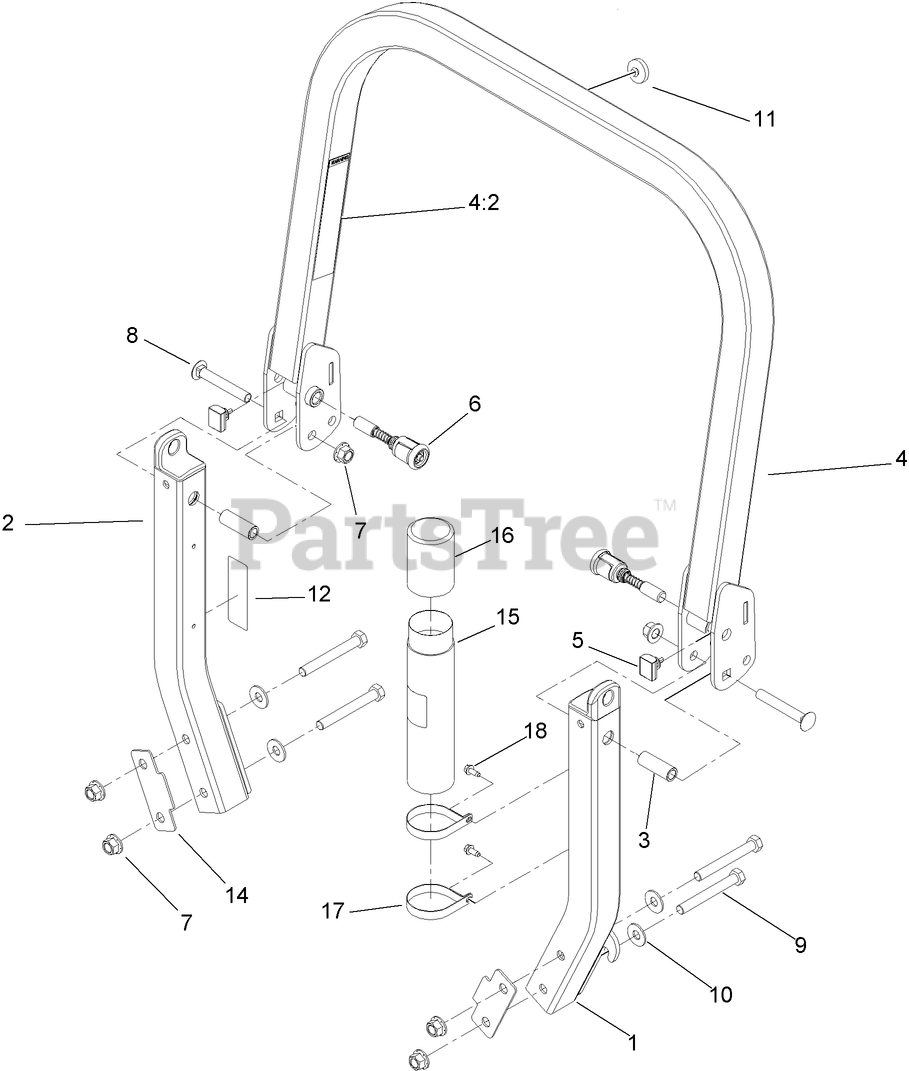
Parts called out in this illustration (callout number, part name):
1	LEG-ROPS, LH
2	LEG-ROPS, RH
3	SPACER
4	UPPER ROPS ASM
4:2	DECAL-WARNING, FOLDING ROPS
5	BUMPER-ROPS
6	PIN-SPRING
7	NUT-LOCK
8	SCREW-CARR
9	SCREW-HH
10	WASHER-SPRING
11	BUMPER-PUSH-IN, RUBBER
12	DECAL-CAUTION
14	SPACER
15	TUBE-MANUAL
16	CAP-HOUSING
17	R-Clamp
18	SCREW-HWH
